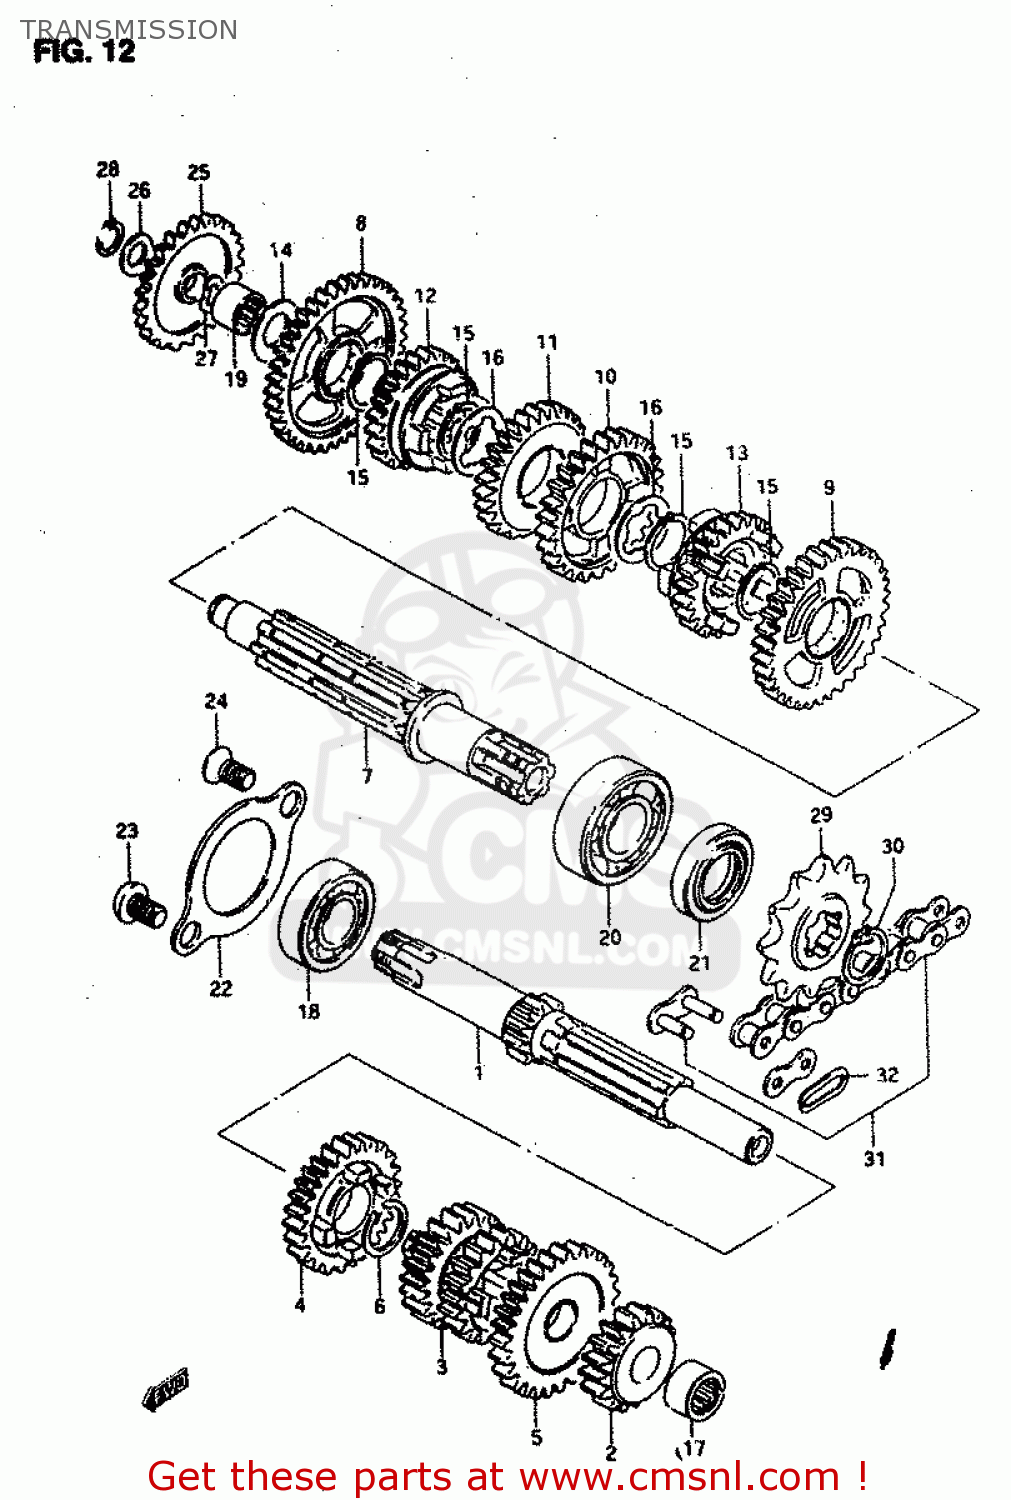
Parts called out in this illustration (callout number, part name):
1	SHAFT,COUNTER
2	GEAR,2ND DRIVE(NT:17)
3	GEAR, 3/4
4	GEAR, 5TH DRIVE
5	GEAR,6TH DRIVE(NT:26)
6	CIRCLIP
7	SHAFT,DRIVE
8	GEAR, 1ST DRIVEN
9	GEAR, 2ND DRIVEN
10	GEAR, 3RD DRIVEN
11	GEAR,4TH DRIVEN(NT:28)
12	GEAR, 5TH DRIVEN
13	GEAR, 6TH DRIVEN
14	RING
15	CIRCLIP
16	WASHER,LOCK
17	ROLLER BEARING (13X19X1
18	BEARING(17X40X12)
19	BEARING(15X21X12)
20	BEARING(20X47X14)
21	OIL SEAL (20X35X5)
22	RETAINER,CNTR SHAFT BEARING
23	SCREW
24	SCREW
25	GEAR,KICK STARTER IDLER(NT:26)
26	THRUST WASHER
27	WASHER
28	CIRCLIP,12 MM
29	SPROCKET,ENGINE(12T)
30	CIRCLIP
31	CHAIN ASSY, DRIVE (48/128)
32	JOINT
33	JOINT,CHAIN(RK)
